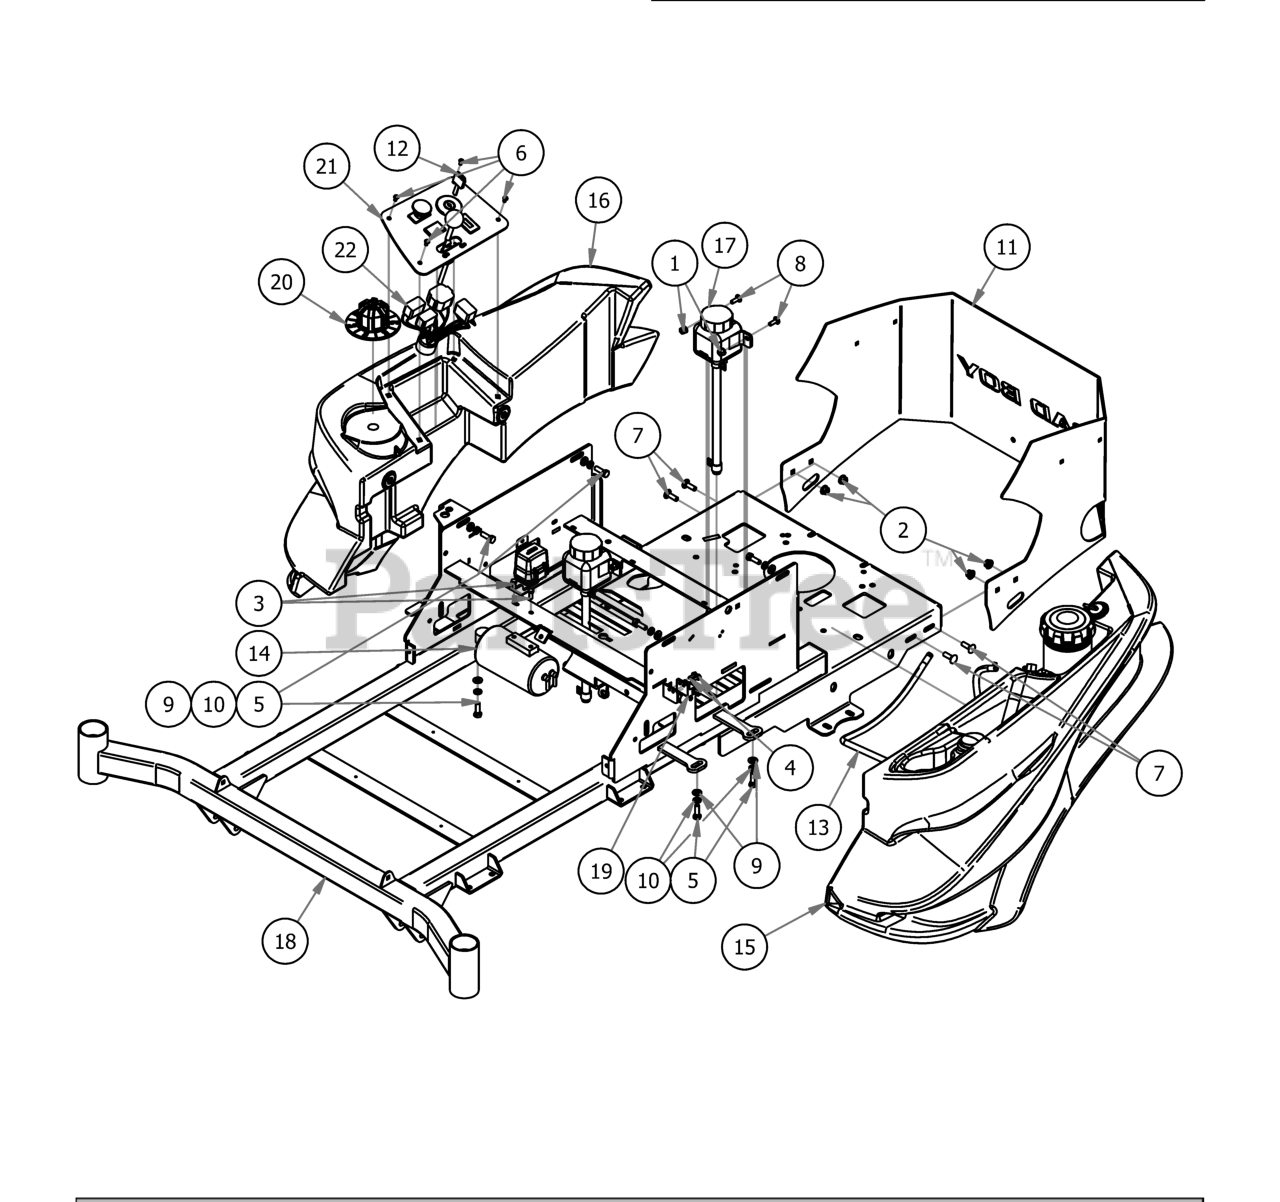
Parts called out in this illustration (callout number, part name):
1	1/4-20 Nylon Insert flange Nut
2	5/16" Nylon Flange Nut
3	M6-1.0 X 16MM Hex Bolt
4	12-24x 1/2 HWH Bolt
5	5/16" x 1" Bolt
6	10-32 x 3/8" Button Socket Head Bolt
7	5/16" x 1" Carriage Bolt
8	1/4" x 3/4" Carriage Bolt
9	5/16" Flat Washer
10	5/16" Lock Washer
11	2017 ZT Rear Plate
12	Ignition Key
13	37" Fuel Line Assembly
14	ZT/Mav EPA Cannister Assy
15	Left Fuel Tank
16	Right Side Console
17	Hydro Tank Assembly
18	2017 MZ/ZT 54"-60" Frame
19	Safety Switch
20	MZ/ZT Deck Height Dial
21	2019 ZT/Maverick Control Panel Assembly
22	Wiring Harness
